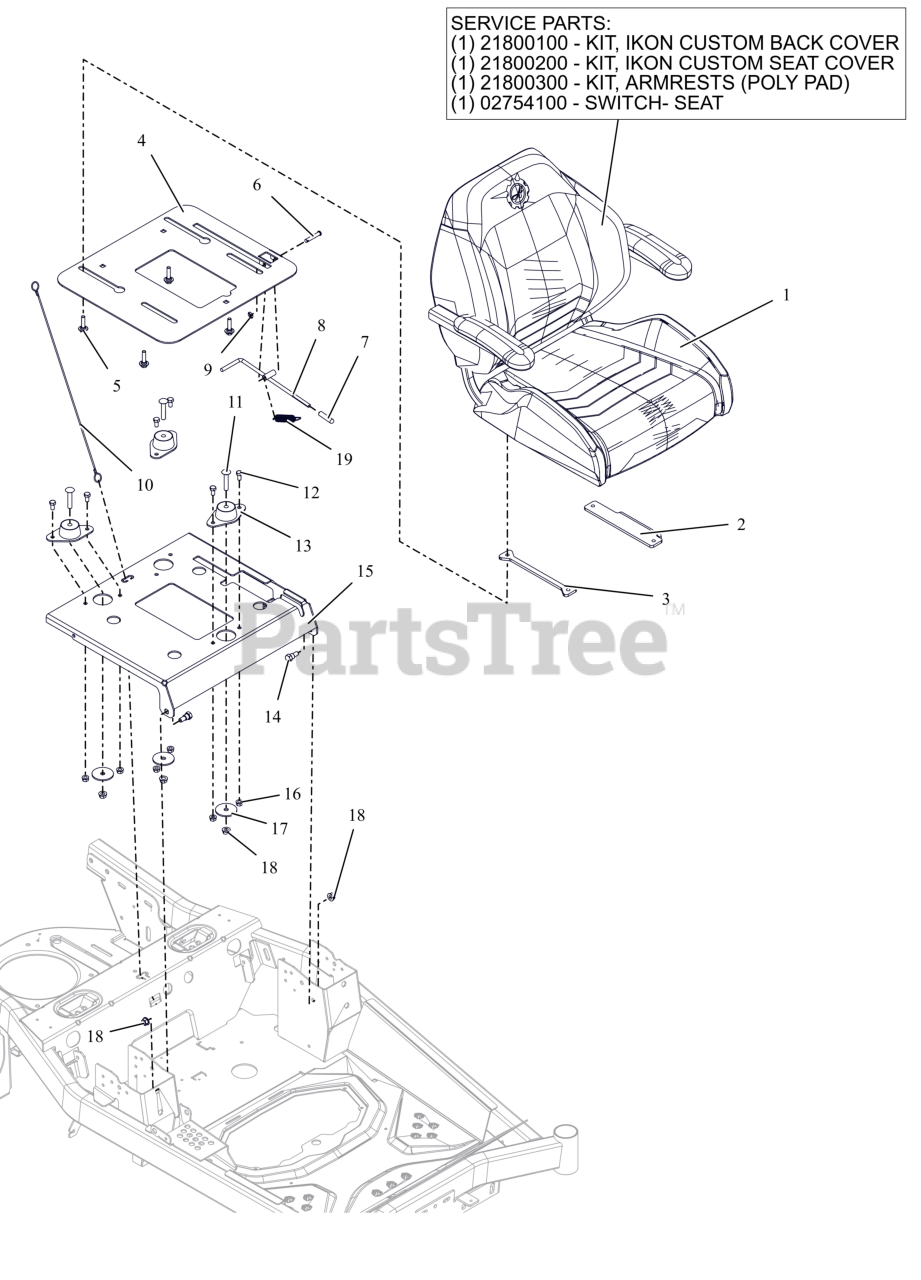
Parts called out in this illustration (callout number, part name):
1	SEAT- IKON 2023 (WOOD)
1	KIT - IKON CUSTOM BACK COVER
1	KIT - IKON CUSTOM SEAT COVER
1	KIT - ARMRESTS (POLY PAD)
1	SWITCH- SNAP MTG N.O.
2	PLATE- SEAT ADJUSTER
3	PLATE, ADJ SEAT SLIDE (BLACK)
4	PLATE- SEAT ISOLATOR (BLK)
5	BOLT SHLDR .31-18 X .175
6	PIN, CLEV .309X1.75 ZCC
7	GRIP, BLACK RD-.312X1.50
8	WLDMT, LATCH SEAT (BLACK)
9	NUT-PUSH .312
10	LANYARD, SEAT CABLE .093X19.5
11	BLT,RHSSN.375-16X2.00 G5 ZCC
12	BLT, HEX .31-18X.625 G5 ZCC
13	MOUNT, FAIL-SAFE COMPRESSION
14	BLT-SHLDR .50X.38 ZCC
15	BRKT- SEAT- ISOLATOR MTG (BLK)
16	NUT,LK-CTR-FLG .31-18 GF ZCC
17	WSHR-FL-STL 0.406X2X0.125 ZCC
18	NUT-LK-CTR-FLG .375-16 GF ZCC
19	SPRG, EXTENSION .063 X .653 X 2.755
